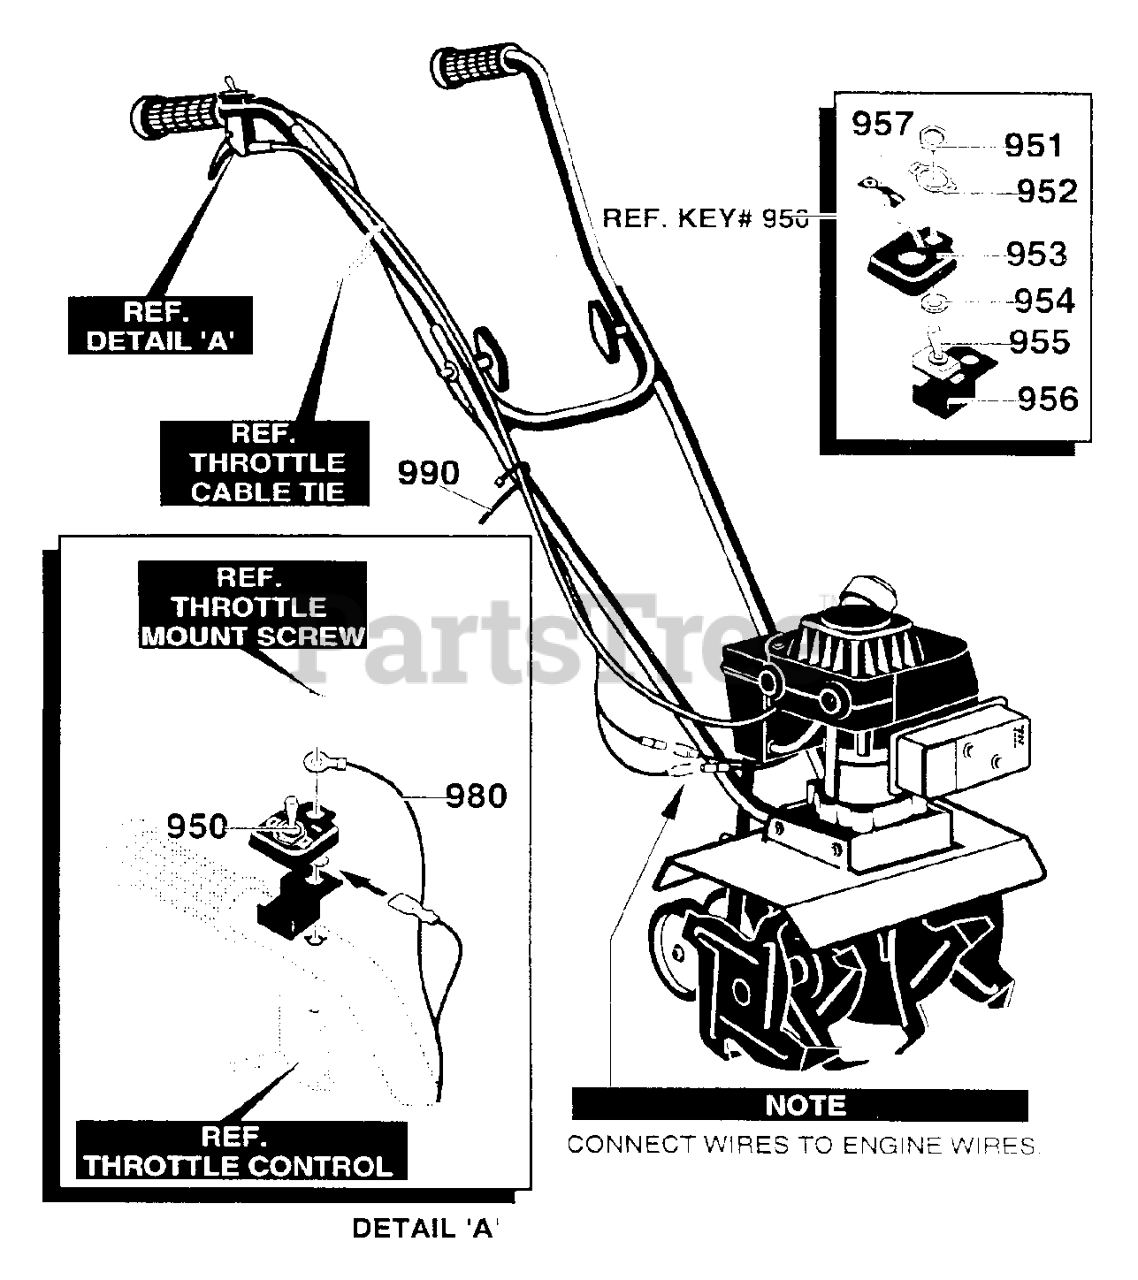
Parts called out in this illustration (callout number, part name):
950	Switch Assembly
951	Plate, Indicator
953	Bracket, Switch
954	Lockwasher
956	Bracket, Switch
957	Decal, On-Off
980	Switch Assembly, Kill
990	Fastener, Cable
